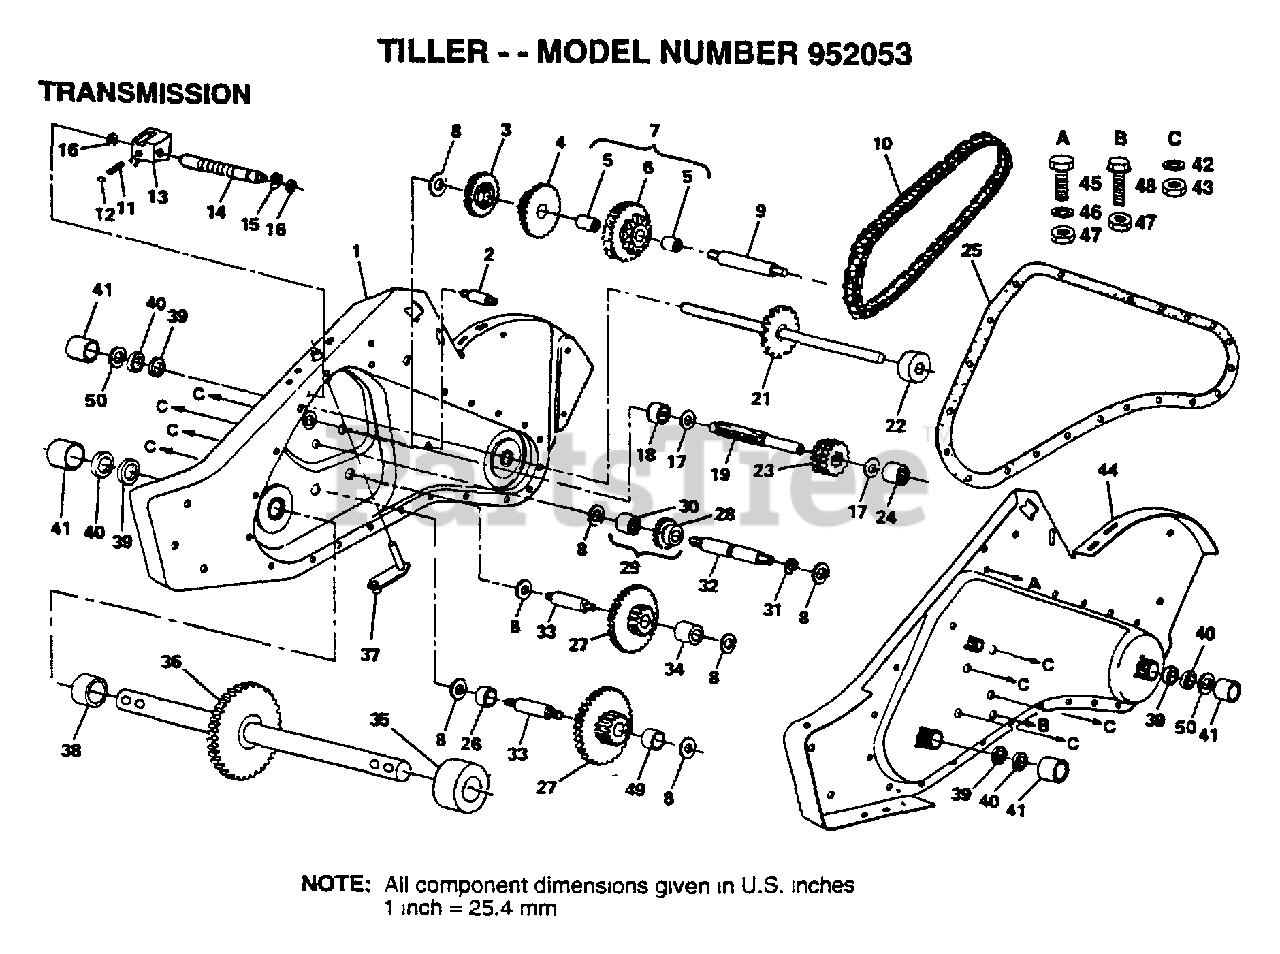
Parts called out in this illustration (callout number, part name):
3	REVERSE GEAR TI
4	CLUSTER GEAR TI
5	"CRT, BEARING"
7	SPROCKET ASSY TI
8	WASHER
9	REDUCTION SHFT TI
10	CHAIN TI
11	SPRING-SHIFT CRT
13	SHIFT FORK TI
14	SHIFT SHAFT TI
15	KLIP RING
16	WASHER SEAL CRT
17	"T, BEARING"
18	"TI, BEARING"
19	SHAFT INPUT T
21	SHAFT TINE CRT
22	SPACER CRT
23	INPUT PINION TI
24	NEEDLE BRNG LT
25	GEARCASE GSKT TI
26	SPACER CRT
27	GEAR CLUSTER CRT
28	REVERSE GEAR TI
29	GEAR ASSY TI
30	NEEDLE BEARING TI
31	KLIP RING
32	REVERSE SHAFT TI
33	SHAFT CRT
34	SPACER CRT
35	SPACER CRT
36	SHAFT ASSY CRT
37	BRACKET ASM SHIFT
38	SPACER CRT
39	OIL SEAL STD
40	SEAL RING RUBBER
41	CUP.FORMED.
42	LOCKWASHER
43	NUT.ASF.HEX.7/16
45	BOLT
46	LOCKWASHER
47	NUT.HEX.5/16-18
48	BOLT TI
49	SPACER CRT
50	RING SPIRAL CRT
